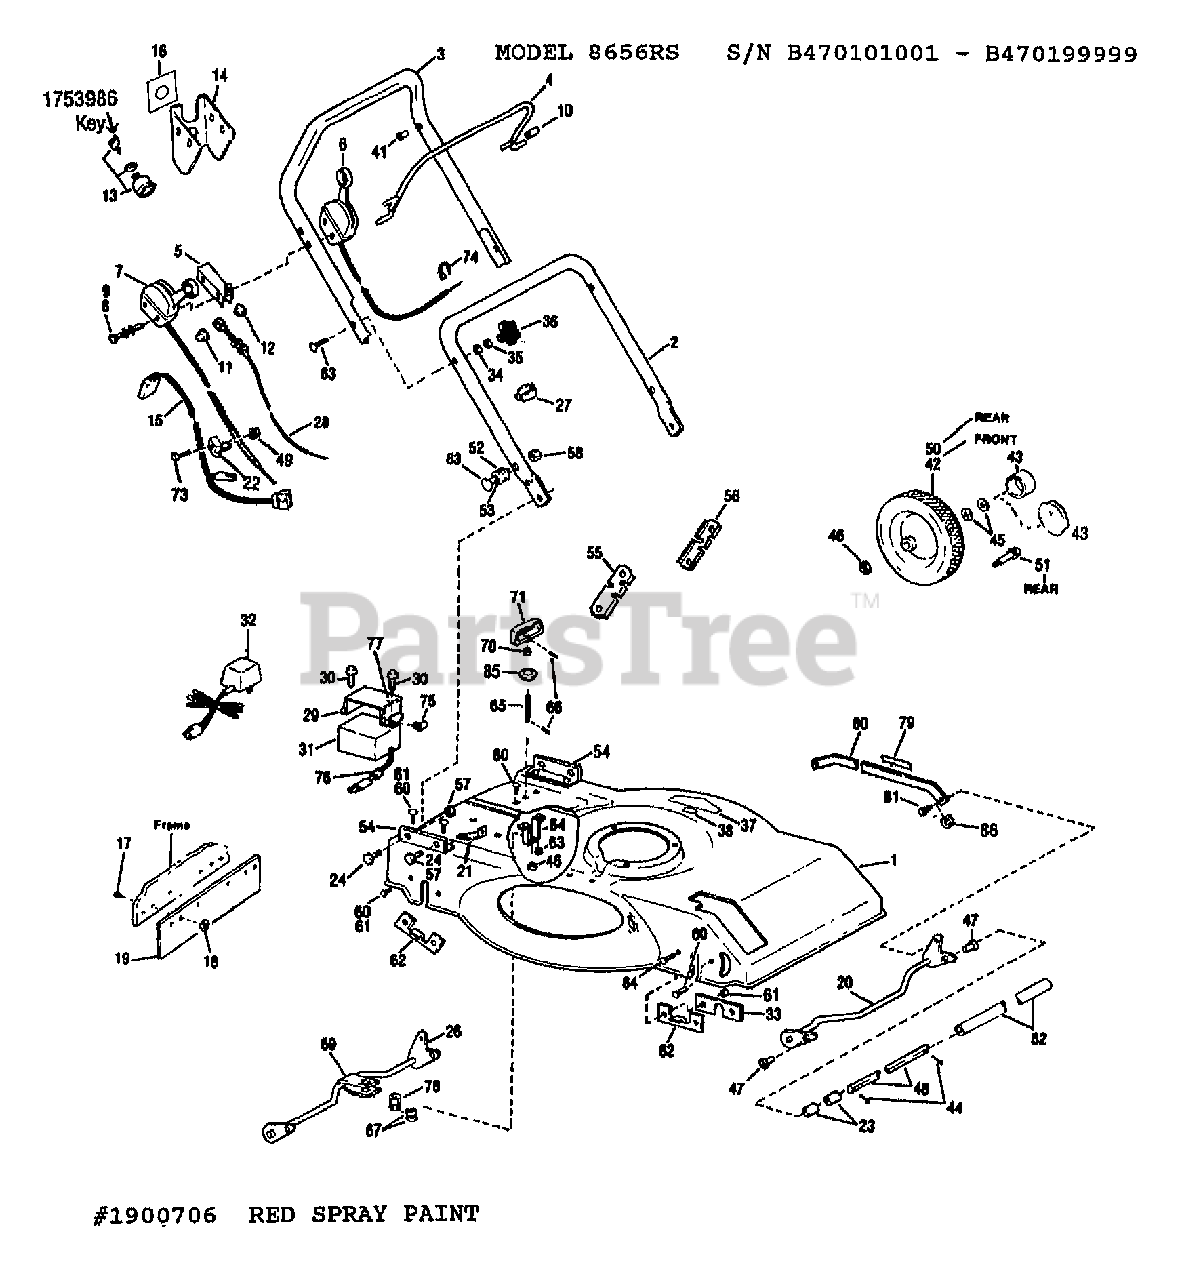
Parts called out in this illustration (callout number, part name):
1	ASSM-BASE W/DECAL MULCHER
2	HANDLE-LOWER BLACK
2	HANDLE-LOWER CHROME
3	HANDLE-UPPER BLACK
3	HANDLE-UPPER CHROME
4	ASSM-BAIL ENGINE CONTROL BLACK
4	ASSM-BAIL ENGINE CONTROL CHROME
5	SUPPORT-CONTROL
6	CONTROL-THROTTLE
7	CLUTCH-CONTROL
8	SCR-HH SEMS
8	SCR-HHS {8656}
9	NUT W/LKWASHER 10-24 ZP
10	GRIP-HANDLE
11	CAP-PUSH ON .312 DIA
12	RING-GRIP EXT .312 ID
13	SWITCH-EL IGNITION {8656}
13	KEY-IGNITION
14	SUPPORT-SWITCH {8656}
15	WIRING HARNESS (8656 MODELS)
15	HARNESS-WIRE {8656}
16	DECAL-ELEC START {8656}
17	RIVET-POP
18	WASHER-.88X.2X.059
19	SHIELD-DEFLECTOR
20	ASSM-FRONT AXLE
22	CLAMP-POWDEN WIRE
23	BUSHING-NYLON
24	SCR-HH 3/8-16X.75 G5 ZP
26	ASSM-AXLE REAR
27	CLIP-WIRE {8656}
27	CONTROL WIRE CLIP (8654, 8655 MODELS)
28	CABLE-ENGINE BRAKE
28	ENGINE BRAKE CABLE
28	CABLE-ENGINE BRKT {8654RS}
29	CLAMP-BATTERY {8656}
30	SCR-FLANGE 1/4-20X3/4 GR5
31	KIT-BATTERY REPLACE {8656}
32	CHARGER-ELEC BATTERY {8656}
33	DOUBLER-PLATE
34	WASHER-LK .312 ZP
35	WASHER-FLAT 5/16 SAE
37	DECAL-OPEI CAUTION
38	INDICATOR ARROW DECAL
38	DECAL-INDICATOR ARROW (A)
38	DECAL-HT INDICATOR (B)
41	BEARING-FLANGED
42	FRONT WHEEL AND TIRE ASSEMBLY
42	ASSM-FRT TIRE&WHEEL (A)
42	TIRE/WHEEL FRONT F/TB MULCH MW (B)
43	HUB CAP
43	CAP-HUB 1.3/8" DIA. (A)
43	CAP-HUB T/B MULCHERS 3.00" DIA. (B)
44	PIN-COTTER .125 X .75 ZP
45	WASHER-1.375X.523X.059
46	WASHER-FLAT .88X.5X.06 ZP
47	BEARING-AXLE
48	AXLE-DRIVE
49	NUT-HFLK 10-24
50	REAR WHEEL AND TIRE ASSEMBLY
50	ASSM-REAR TIRE & WHEEL (A)
50	ASSM-TIRE & WHEEL (B)
51	SHOULDER SCREW
51	SCR-SHLDR 3/8-16 (B)
52	SPRING-COMPRESSION
53	SPACER
54	BRKT-HANDLEBAR
55	SUPPORT-HANDLE RH
56	SUPPORT-HANDLE LH
57	NUT-LOCK 3/8-16
58	NUT-HFT/LK
60	SCR-CARR 5/16-18X.62 G2 ZP
61	NUT-HFLK 5/16-18 ZP
62	BRACKET-AXLE
64	BRKT-HGT ADJ
65	SCR-HGT ADJ
66	PIN-ROLL .188X1.0
67	RING-RET "E" .668 ID
69	CHANNEL-ADJUST SCR
71	HANDLE-HEIGHT ADJ
73	SCR-HW M10-24X.88 EXTTOOTH
74	TIE-CABLE NYLON BLACK {8656}
75	CLAMP-WIRE {8656}
76	DECAL-CHARGING INST {8656}
77	PAD-BATTERY {8656}
78	NUT-HGT ADJUSTMENT
79	INDICAATOR SCALE DECAL
79	DECAL-INDICATOR SCALE (A)
80	KIT-HEIGHT ADJ LINK
81	SHOULDER BOLT
81	BOLT-SHOULDER GR. 5 (A)
81	SCR-SHOULDER (B)
82	TUBING-PLASTIC
83	SCR-CURVED HD 5/16-18X2.0
84	SCR-TRUSS HD 5/16-18X.62
85	WASHER-RUBBER
86	NYLINER BEARING (B)
86	BEARING-NYLINER
